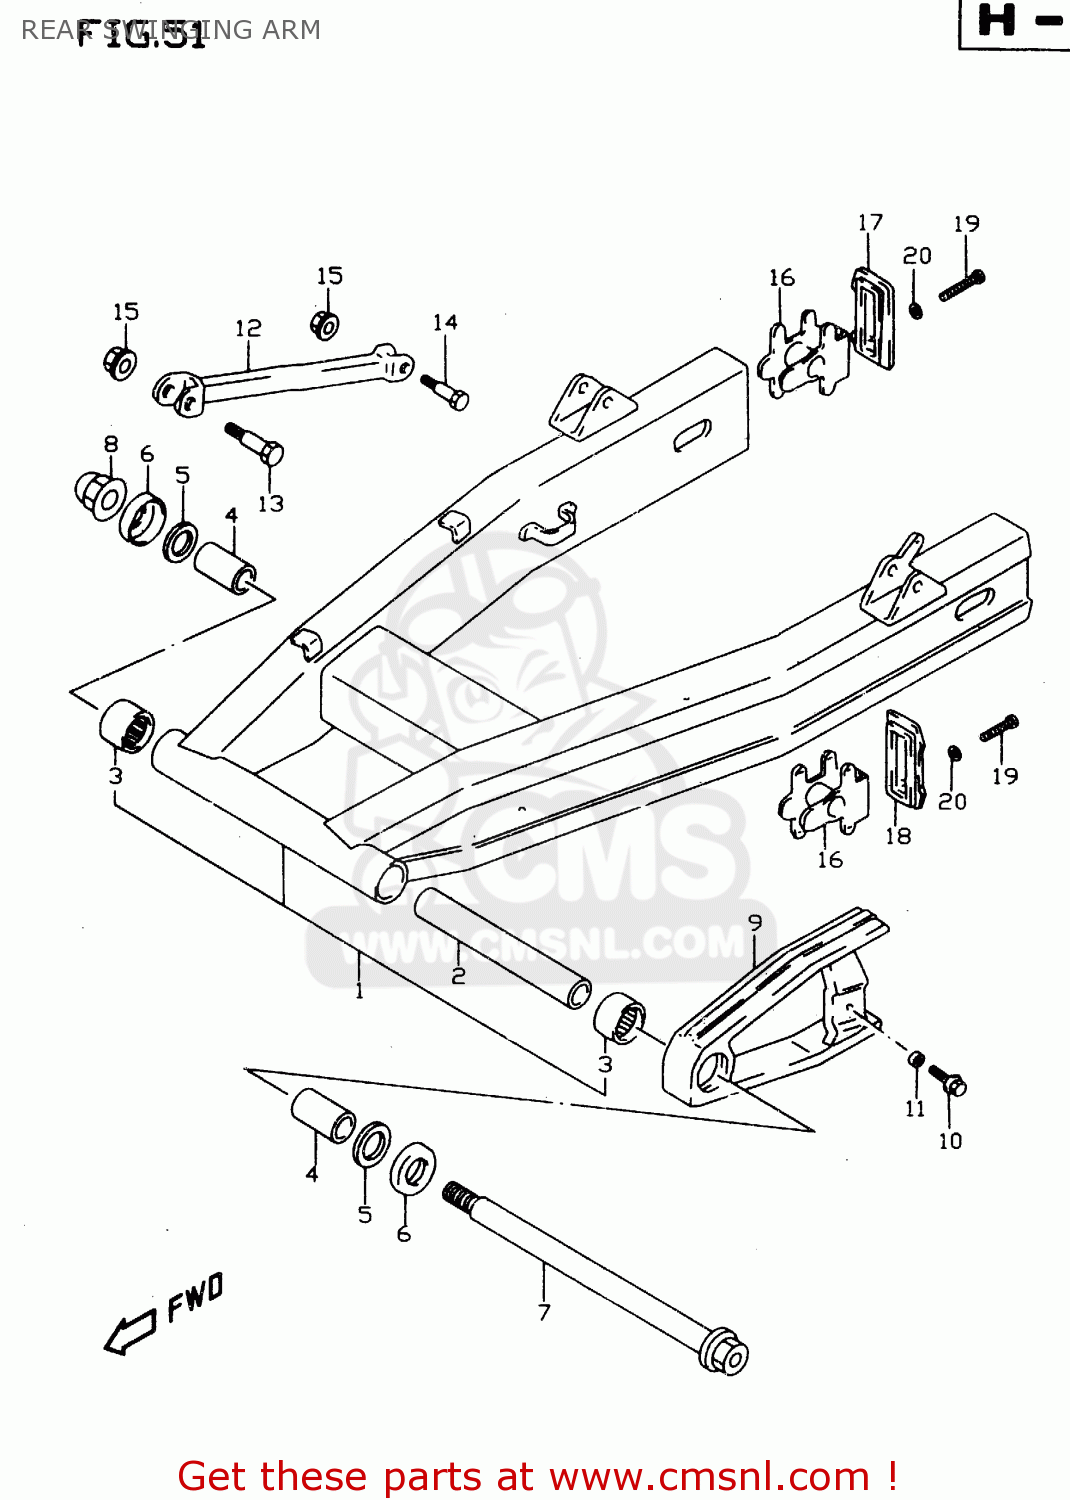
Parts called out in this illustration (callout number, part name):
1	SWINGINGARM ASSY,RR
2	SPACER(20.8X27.2X161)
3	BEARING(25X33X30)
4	SPACER,RR SWGARM PIVOT
5	WASHER
6	DUST SEAL,RR SWGARM PIVOT
7	SHAFT,RR SWINGINGARM PIVOT
8	NUT ,18MM
9	BUFFER,CHAIN TOUCH DEFENSE
10	BOLT 6X20,WITH PLAIN WASHER
11	SPACER(6.5X10X7)
12	TORQUELINK,RR
13	BOLT(10X39)
14	BOLT(10X34)
15	NUT
16	ADJUSTER,CHAIN
17	PLATE,CHAIN ADJUSTER GUIDE,R
18	PLATE,CHAIN ADJUSTER GUIDE,L
19	BOLT(8X50)
20	WASHER
